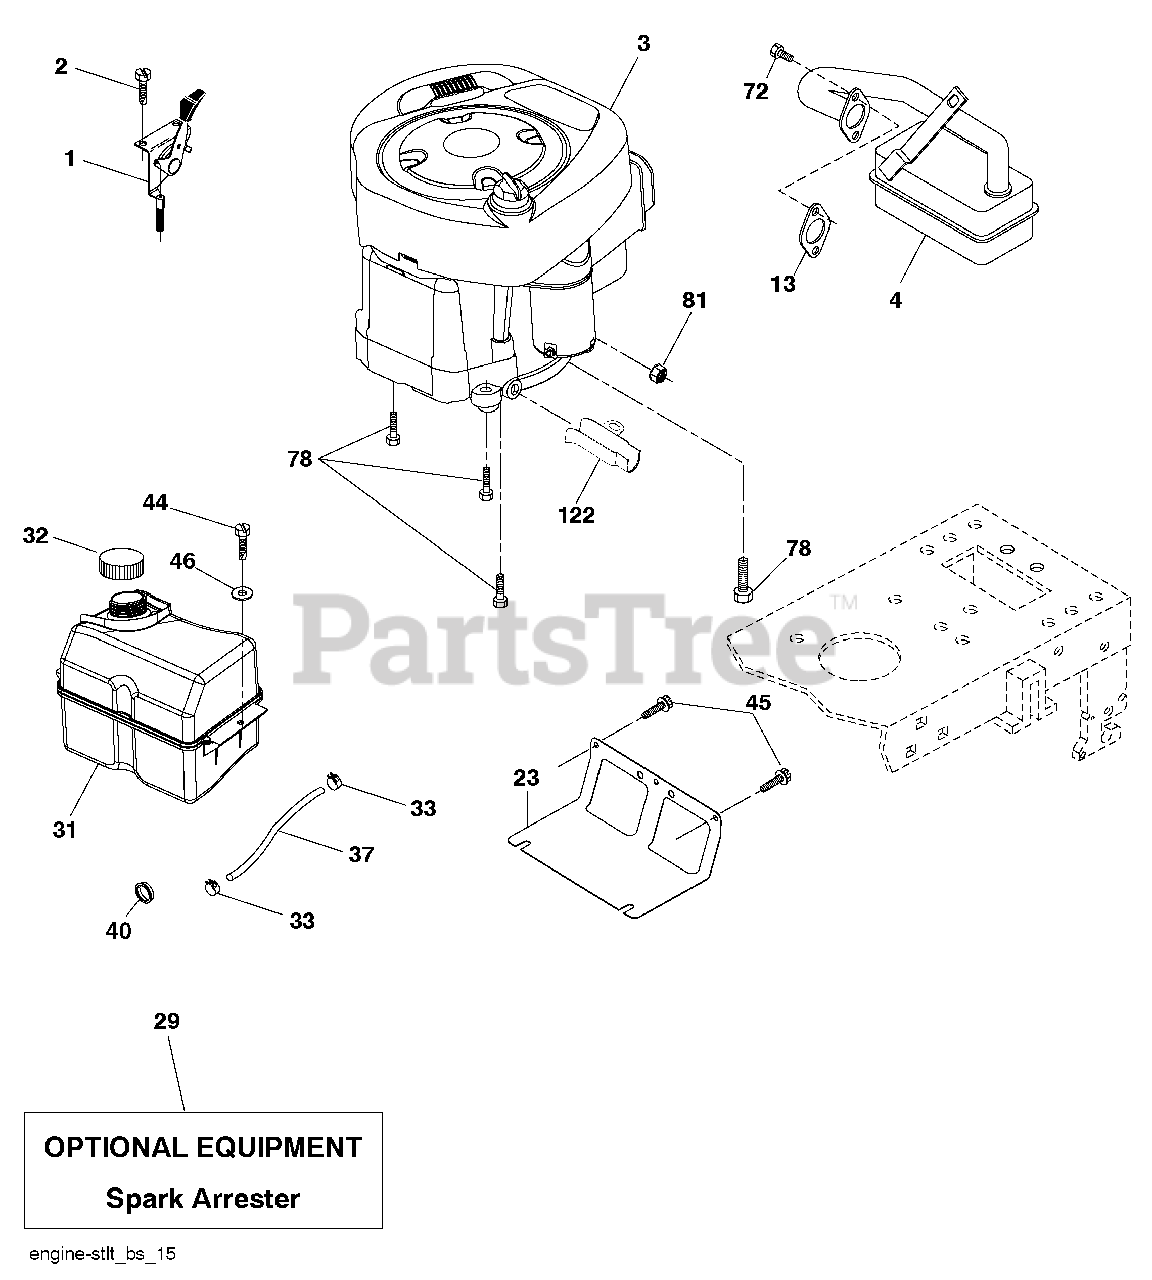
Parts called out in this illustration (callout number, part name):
1	Control Th/ch Flag
2	Screw Hex Thd Cut 1/4-20 x 1/2
4	Muffler Exhaust B&S
13	Gasket Eng 1 313 Id Tin Plated
23	Shield BRN/DBR Guard
29	Kit Spark Arrester (Flat Scrn)
31	Tank Fuel Front
32	Cap Asm Fuel
33	Clamp Hose
37	Line Fuel
40	Bushing Snap Nyl Blk Fuel Line
44	Screw Thdrol 1/4-20 x 3/4
45	Screw Hex Wsh Thdrol 3/8-16
46	Washer 9/32 x 7/8 x 16 Ga.
72	Screw Socket Head 5/16-18 x 3/4
78	Screw 3/8-16 x 1-1/4
81	Nut Keps Hex 1/4-20 unc
122	Extension Drain Oil
